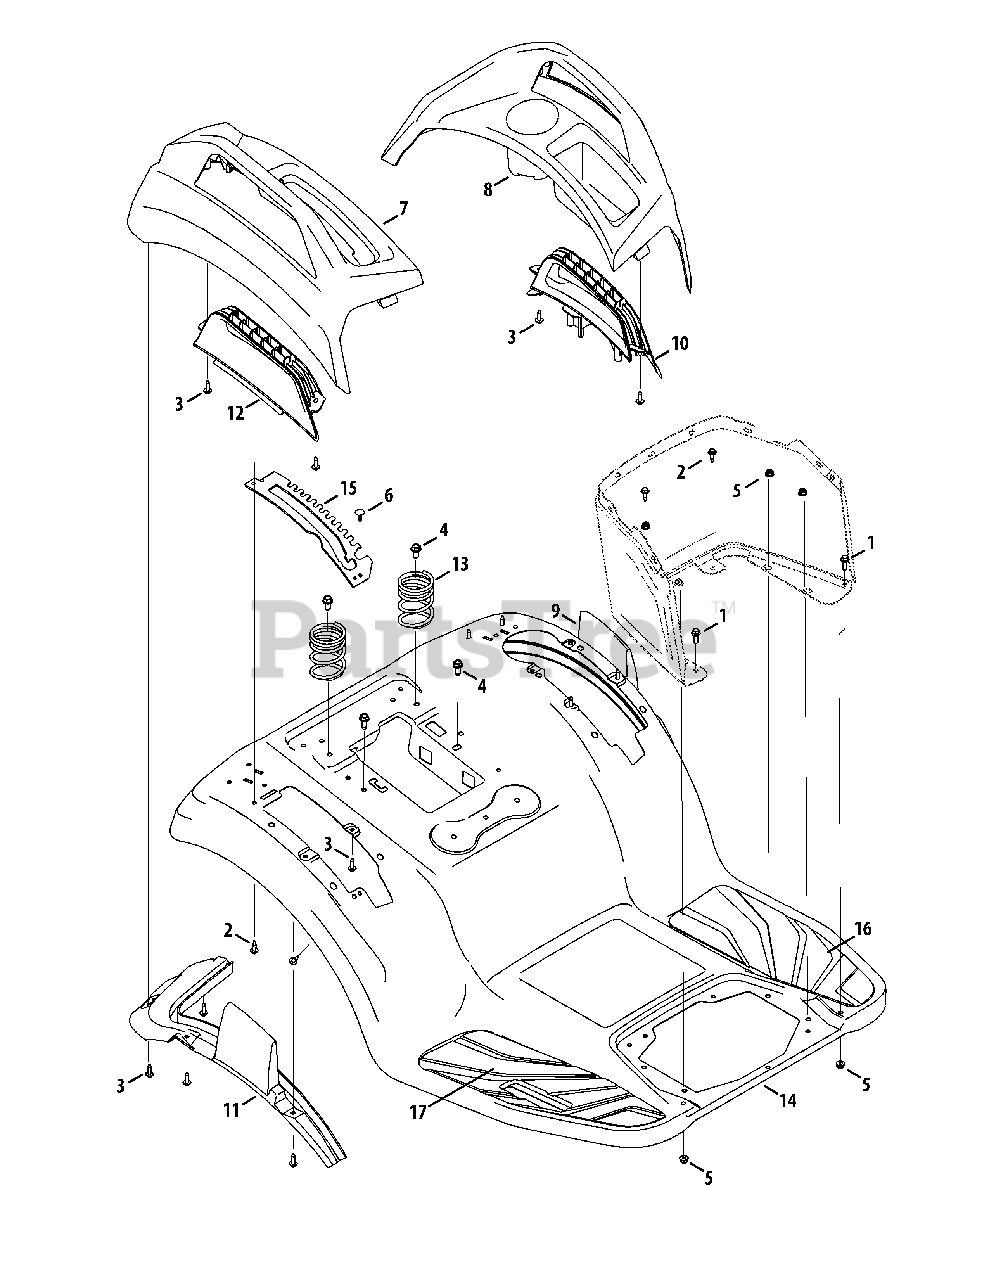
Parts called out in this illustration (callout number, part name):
1	Hex flange Screw, 1/4-20 x .75
2	Screw, M6-1 x .625
3	Screw, 1/4-10 x .75
4	Screw, Self-tapping, 5/16-18, 0.750,
5	Nut, Flange Lock, 1/4-20, Nylon
6	Ratchet Clip, .250 DIA
7	Upper Cover, RH
8	Upper Cover, LH
9	Lower Cover, LH
10	Cover Handle, LH
11	Lower Cover, RH
12	Cover Handle. RH
13	Compression Spring, 2.50 x 3.951 x .207
14	Fender
16	Pad, Foot, LH
17	Pad, Foot, RH
